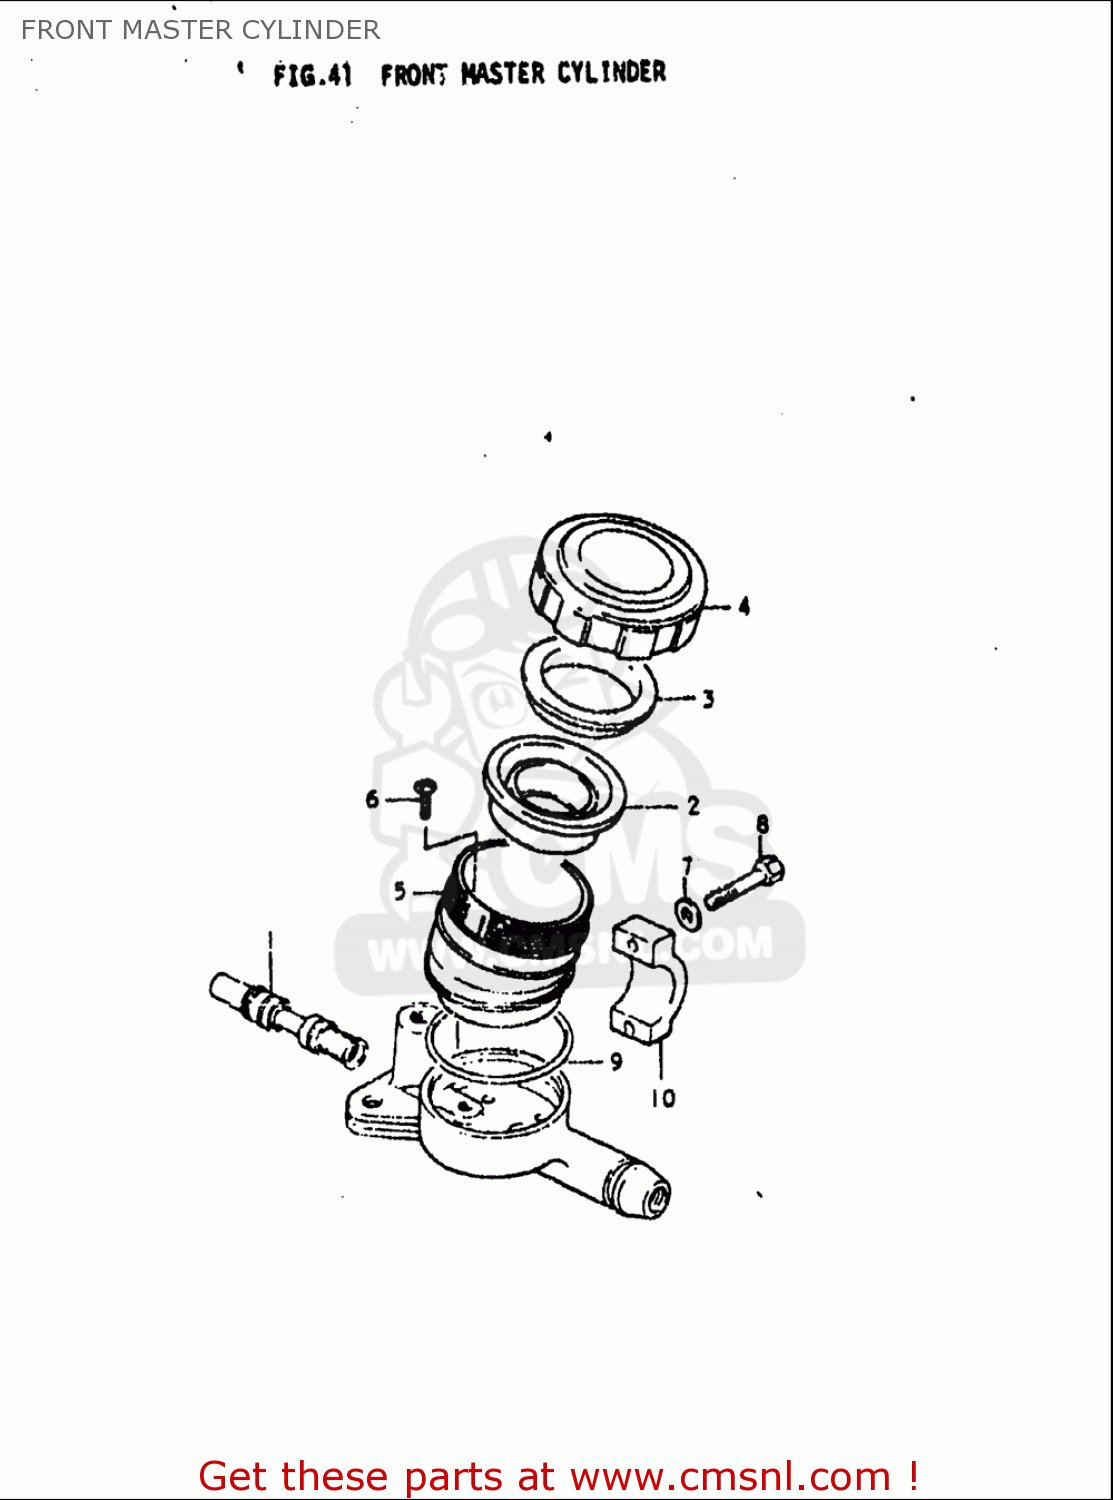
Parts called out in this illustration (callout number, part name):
1	PISTON & CUP SET
2	DIAPHRAGM
3	PLATE
5	RESERVOIR
7	WASHER
8	BOLT
9	O RING
